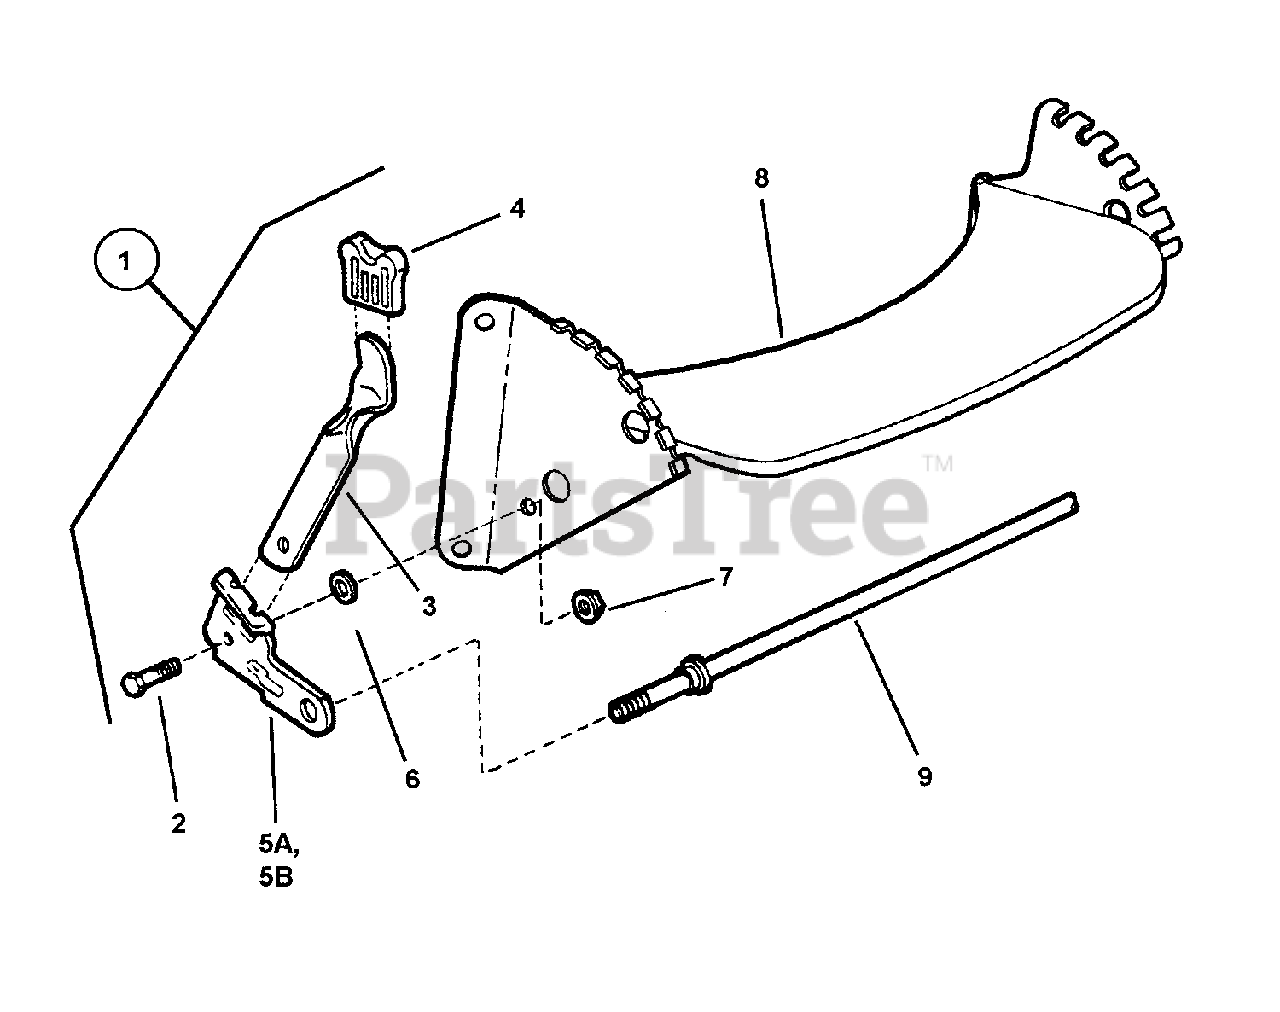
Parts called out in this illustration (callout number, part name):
1	ASSEMBLY, Right Wheel Arm
2	BOLT, 5/16-18 Hex Washer Face Shoulder
3	LATCH, Height
4	GRIP, Height Latch
5B	WHEEL ARM, R.H. Front (Round Hole)
6	RETAINER, 5/16" Bolt
7	NUT, 5/16-18 Hex Flange Lock, GR 5
8	WELDMENT, Front Wheel Bracket
9	AXLE, 21"
